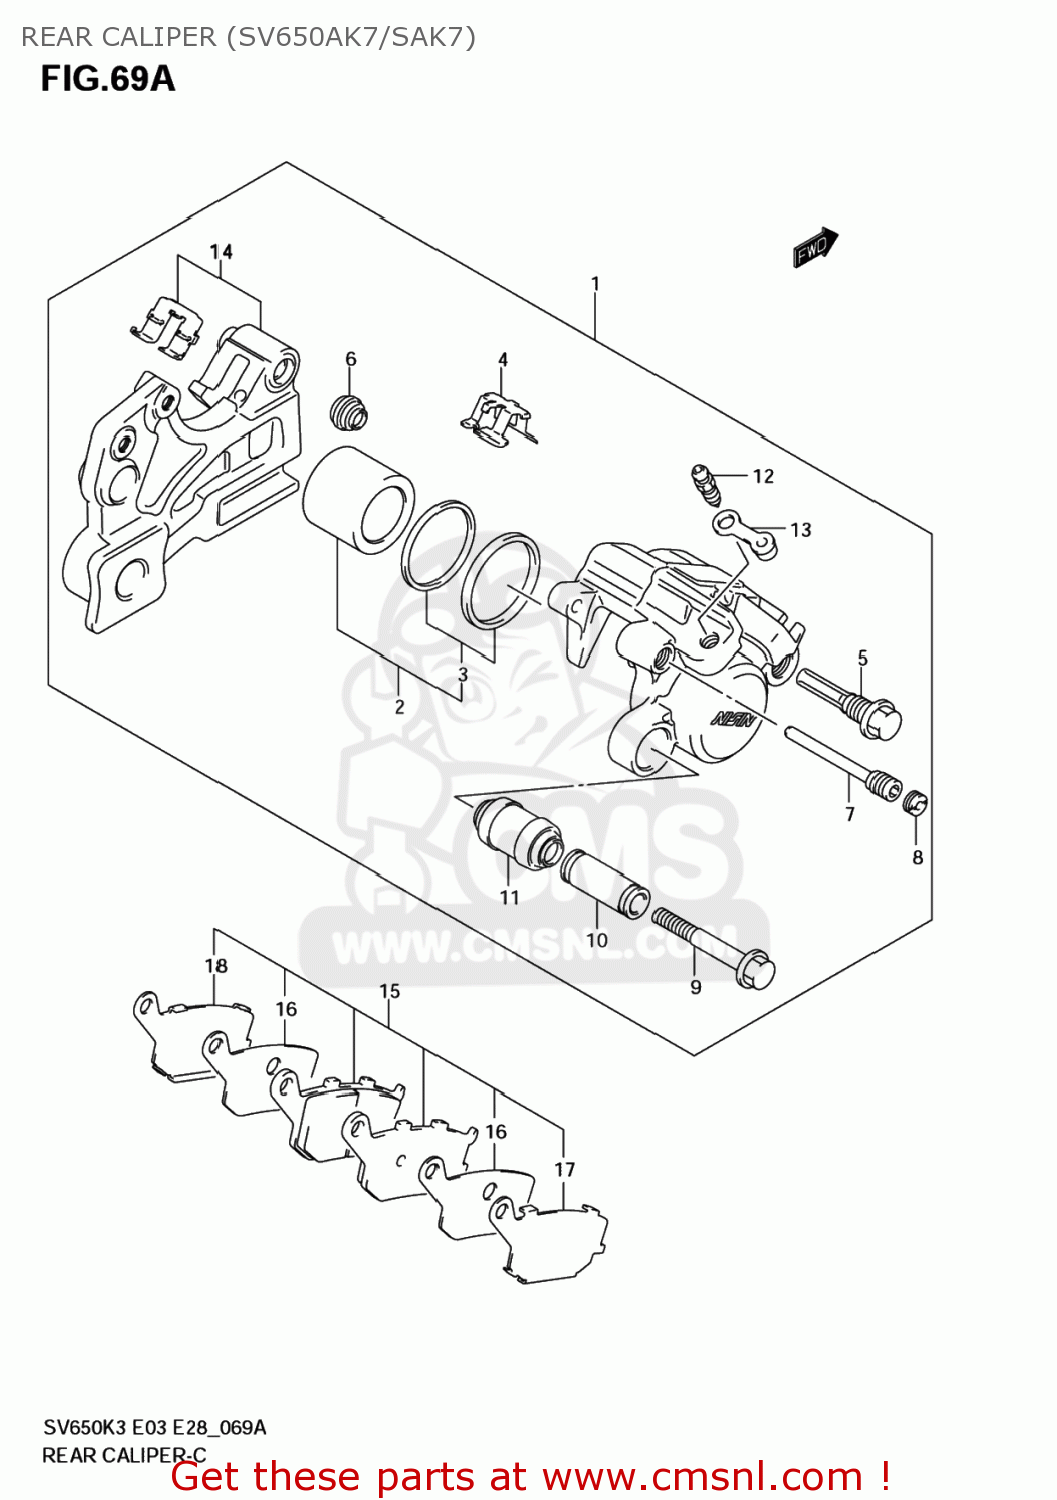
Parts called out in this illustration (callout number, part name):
1	CALIPER ASSY,RE
2	PISTON SET
3	SEAL SET,PISTON
4	SPRING,PAD
5	BOLT
6	BOOT
7	PIN,PAD
8	PLUG,PIN
9	BOLT
10	SLEEVE
11	BOOT,SLEEVE
12	BLEEDER
13	CAP,BLEEDER
14	BRACKET
15	PAD & RETAINER
16	INSULATOR
17	RETAINER
18	RETAINER
